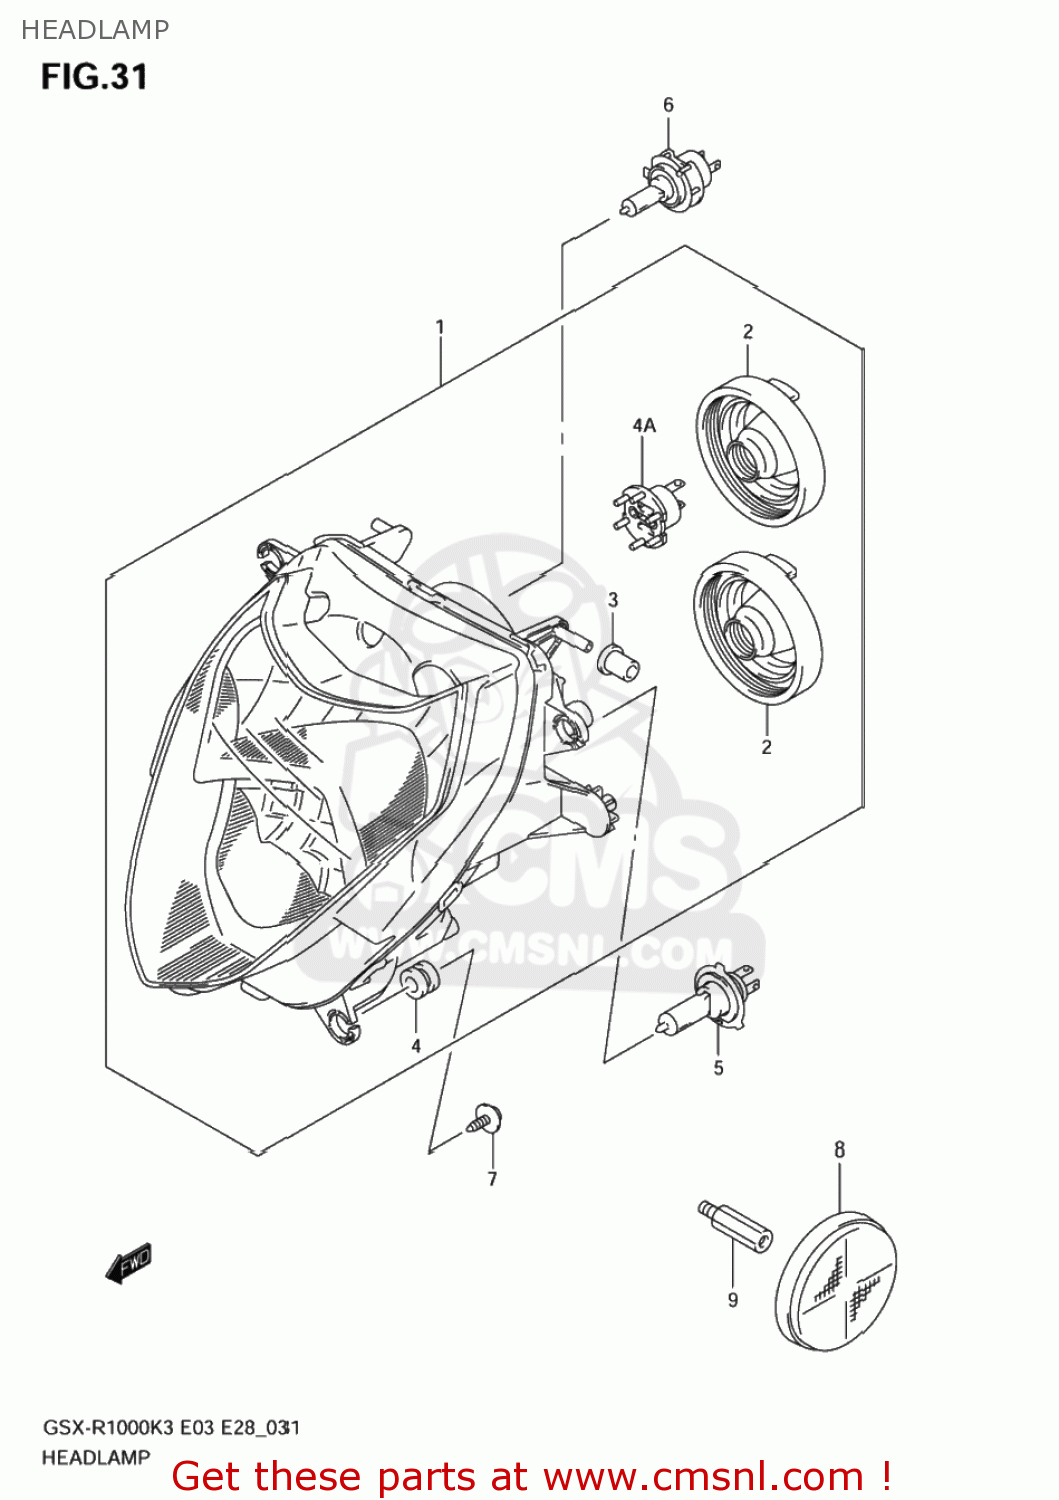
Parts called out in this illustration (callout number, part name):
1	HEADLAMP ASSY
2	COVER,SOCKET
3	CUSHION
4	CUSHION
4A	ADAPTER ASSY
5	BULB(12V60/55W,H4)
6	BULB(12V55W/H7/PX26D/PHILIPS)
7	SCREW(5X15)
8	REFLECTOR,REFLEX FR
9	BOLT
